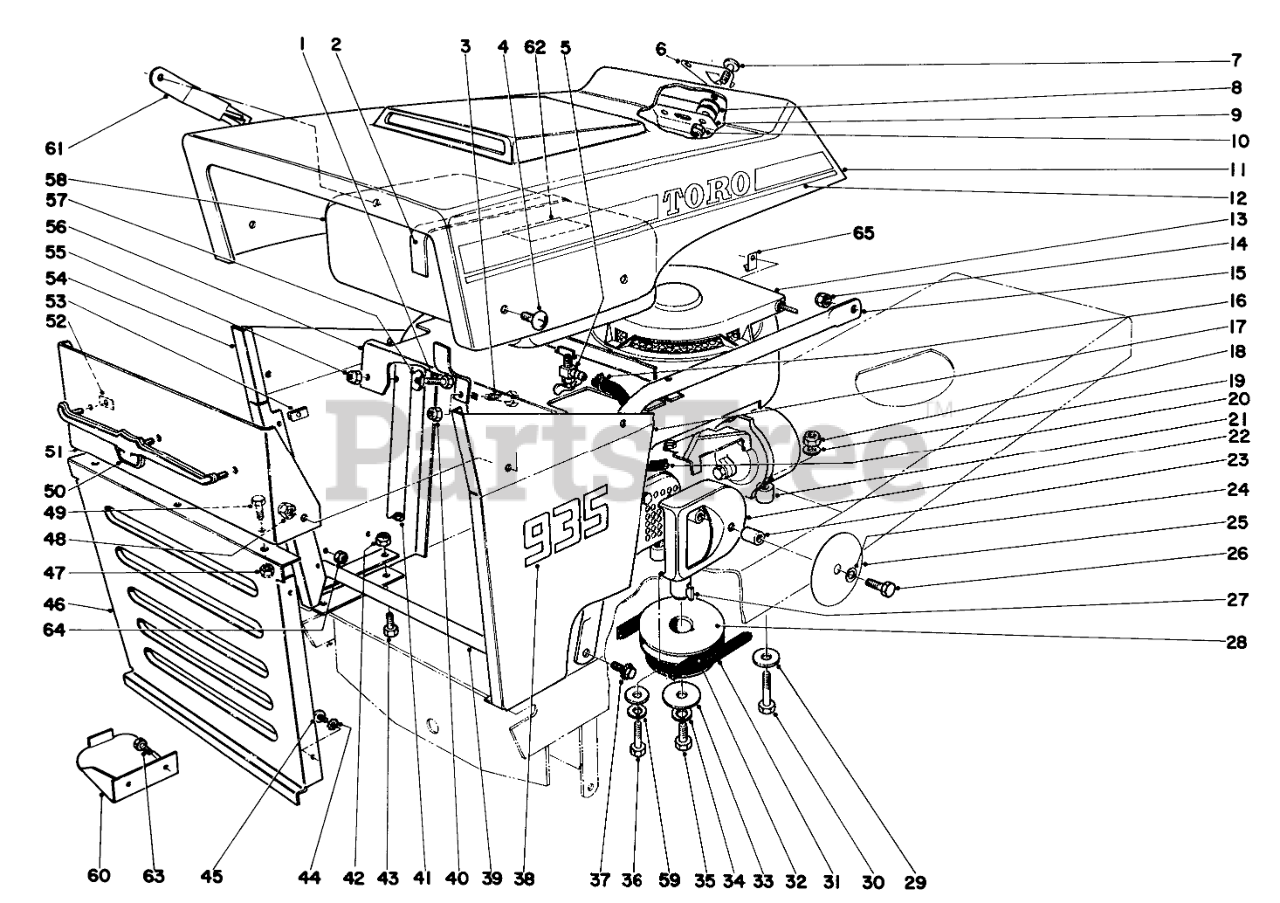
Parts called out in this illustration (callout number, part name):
1	SCREW-HH
2	Strap Gas Tank
3	SCREW-HH
4	Truss Head Screw
5	Hose Fitting
6	Hood Clip
8	WASHER-FLAT
9	Hood Latch
12	Decal Hood Left
13	Engine 935
15	Support Gas Tank Left
16	CLAMP-HOSE
17	Skin Left Front
18	Nut
19	WASHER-FLAT
21	Spacer
22	Baffle Muffler
23	Spacer Muffler
24	WASHER-LOCK/SP
25	Shield Baffle
26	SCREW-HH
27	WoodruffKey
28	Engine Pulley
29	WASHER-FLAT
30	SCREW-HH
31	V BELT TRACTION
32	V BELT PTO
33	WASHER-FLAT
34	WASHER-LOCK
35	SCREW-HH
36	SCREW-HH
38	Decal 935
39	Hinge
41	Support Gas Tank Right
43	SCREW-HH
44	WASHER-LOCK, EXT
46	Grille
48	Nut
49	SCREW-HH
50	Bullshead
51	Blank Headlamp
52	Tinnerman Nut
53	NUT-CLIP,U
54	Skin Right Front
56	Bracket Gas Tank
57	WASHER
58	Gas Tank
59	WASHER-LOCK
60	Trimmer Support
61	Bracket Trimmer
62	Decal
63	SCREW-HH
64	NUT-LOCK, CONE
